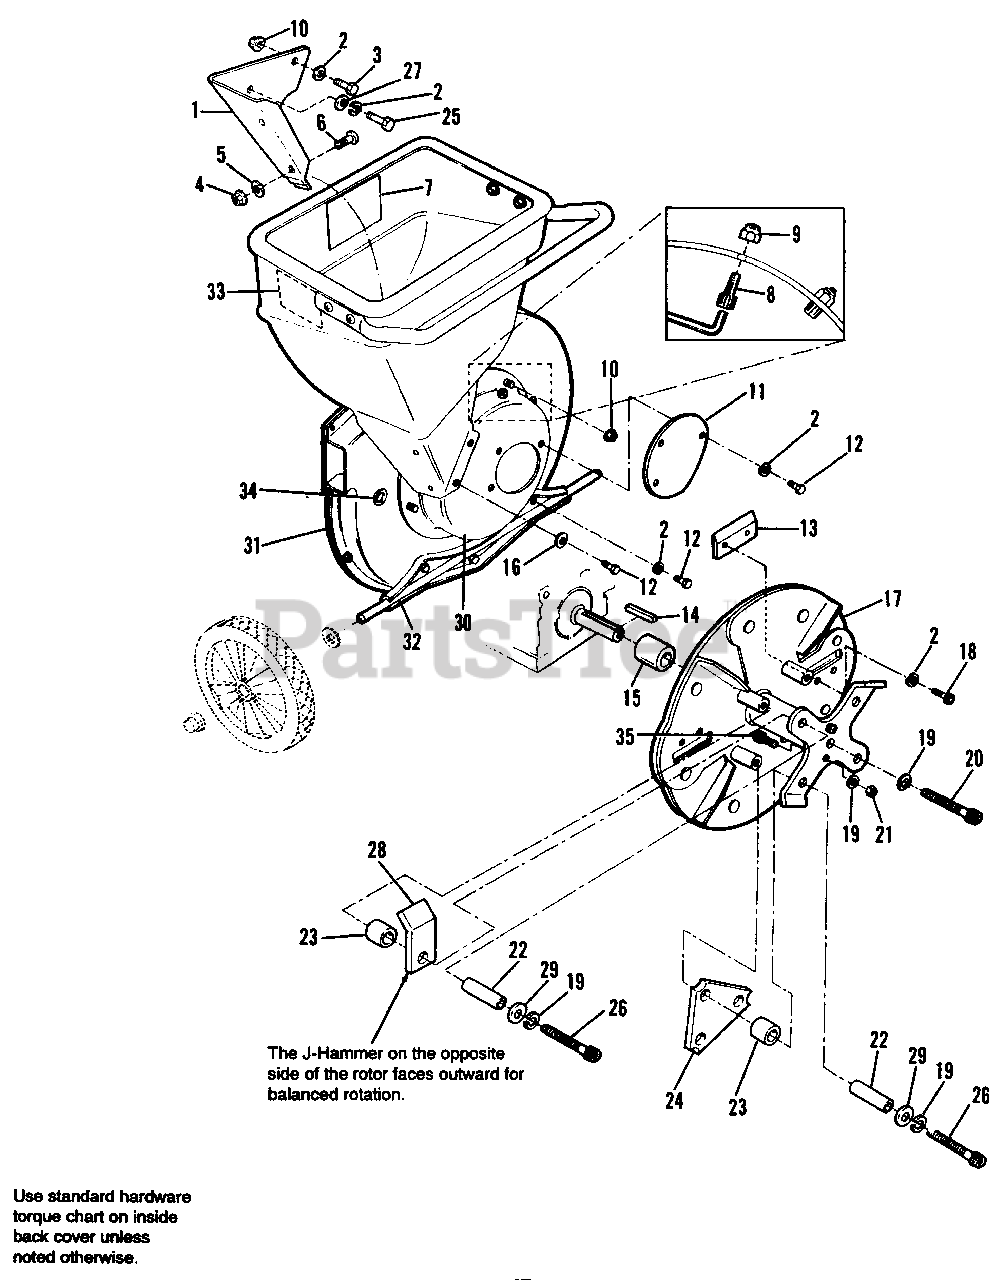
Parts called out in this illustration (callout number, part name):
1	HOPPER LINER
2	LOCKWASHER, Split, 5/16
3	CAPSCREW, Hex Hd., 5/16-18 x 1
4	NUT, 2-Way Lock, 1/4-20
5	WASHER, Flat, 1/4
6	CAPSCREW, Phillips Hd., 1/4-20 x 5/8
7	DECAL, CAUTION
8	CAPSCREW, Socket Hd., 5/16-18 x 1/2
9	NUT, Nylock, 5/16-18
10	NUT, Flange, Hex, 5/16-18
11	COVER, RotorHousing
12	CAPSCREW, Hex Hd., 5/16-18 x 1/2
13	CHIPPER KNIFE
14	KEY, 1/4 Sq. x 1-7/8
15	SPACER, Rotor, 1"
16	WASHER, Flat, 5/16
17	ROTOR, 1" Hub
18	CAPSCREW, Socket Hd., 5/16-24 x 5/8
19	LOCKWASHER, Split, 3/8
20	CAPSCREW, Socket Hd., 3/8-24 x 2
21	NUT, Hex, 3/8 16
22	SPACER, Tube
23	SPACER, 3/4 O.D., 3/4 Long
24	HAMMER, Trianglar
25	CAPSCREW, Hex Hd., 5/16-18 x 3/4
26	CAPSCREW, Hex Socket Hd., w/Patch, 3/8-16 x 2, Gr. 8
27	WASHER, Flat, 5/16"
29	WASHER, Flat, 7/8 O.D.
30	HOUSING, Rotor
31	HOUSING, Fan
32	AXLE ASSEMBLY
33	DECAL, Danger
34	PLUG BUTTON
35	CAPSCREW, Socket Hd., 3/8-16 x 5/8
